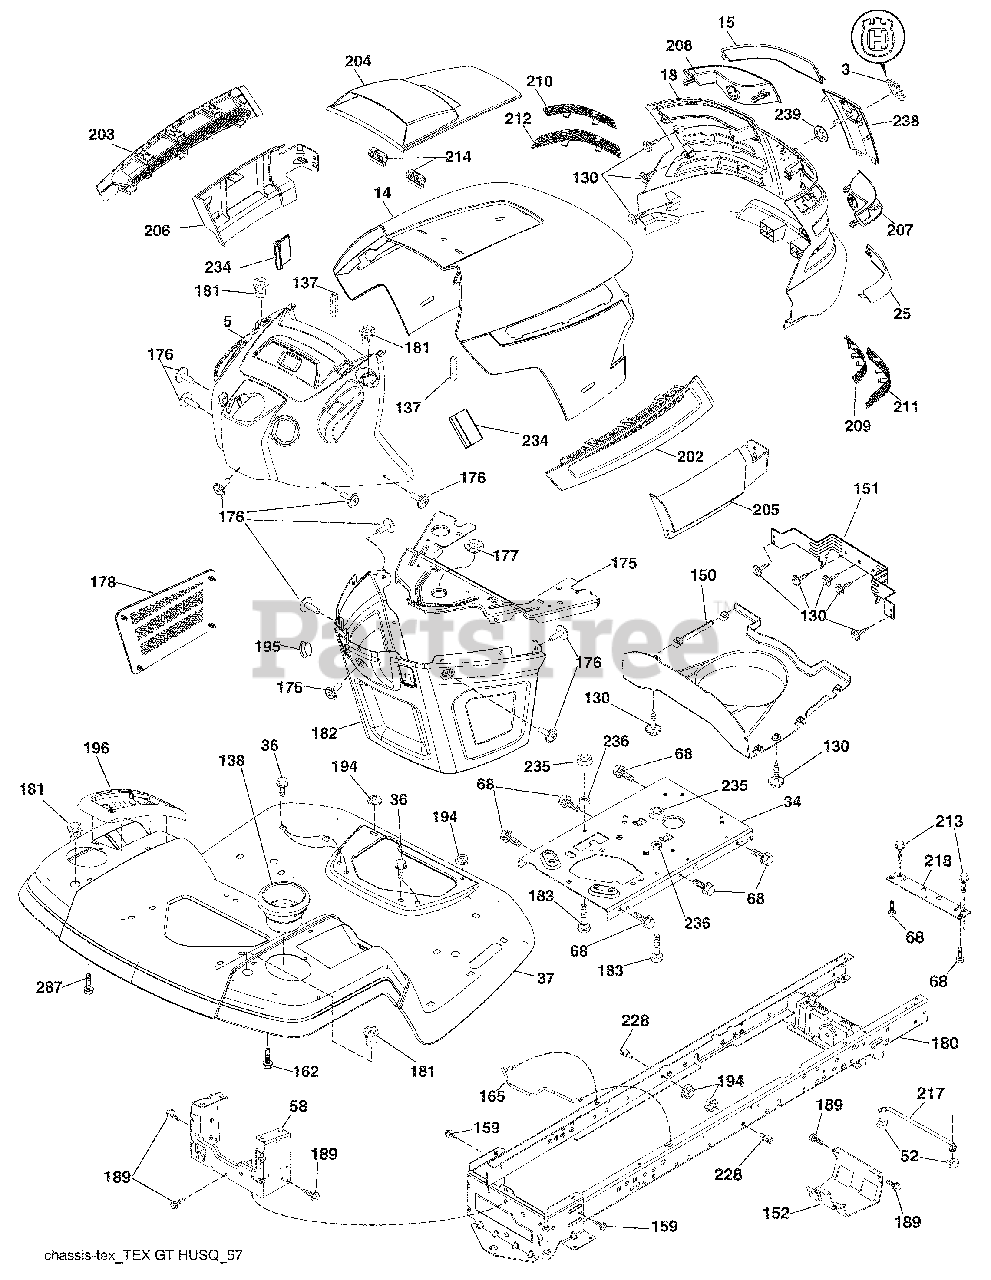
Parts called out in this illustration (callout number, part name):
3	Logo
14	Hood
18	Grille/Lens Asm.
34	Plate Engine
36	Screw 5/16-18 x 3/4
37	Fender
52	Nut Lock 5/16-18
58	Drawbar Upper 2PC Sml. Fender
68	Screw Thdrol 5/16-18 x 1/2
130	Screw #10 x 0.750
137	Bumper Dash
138	Cupholder
151	Bracket Pivot Hood
152	Shield Browning
159	Screw 3/8-16 x 3/4
165	Support Tank Rear
175	Crossmember
176	Screw 10-24 x 5/8
177	Bushing Steering
178	Cargo Net Asm.
181	Bushing Mtg. Fender Crgo
182	Dash Lower
183	Bolt Fin Hex 5/16-18 unc x 1-1/4
189	Screw 5/16-18 x 3/4
194	Nut Lock Hex Flange 5/16-18
195	Plug Hole Dash Lower
196	Console Asm. Deck Lift
202	Vent Side Hood RH
203	Vent Side Hood LH
204	Vent Top Hood
205	Skirt Hood Side RH
206	Skirt Hood Side LH
209	Insert Hex Top RH
210	Insert Hex Top LH
211	Insert Hex Bottom RH
212	Insert Hex Bottom LH
213	Bolt 5/16-18 x 3/4
214	Clip Retainer Tinner
218	X-Piece Hood Stop
228	Stud Fastner
234	Bumper Hood
235	Spacer Fender
236	Nut Lock 5/16-18 unc
287	Screw 1/4-20 x 3/8
